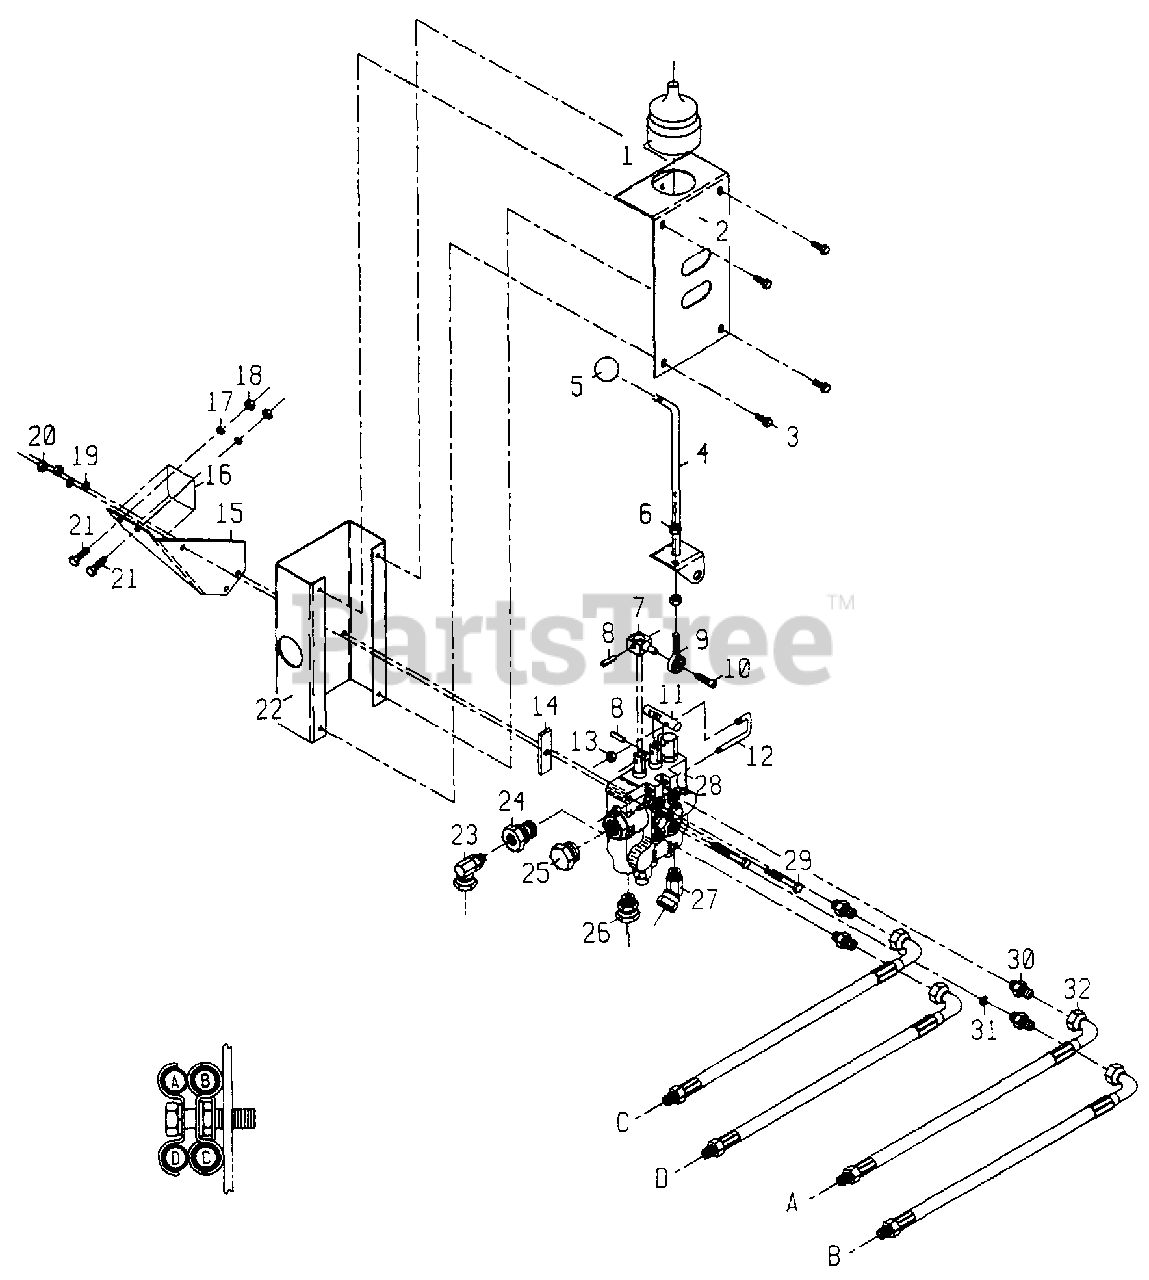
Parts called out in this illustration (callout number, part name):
1	Rubber Boot
2	End Cover
3	1/4 NC x 3/4 Self-tap screw
4	Handle
5	Clip Ball
6	5/16 NF Hex nut
7	Pivot block
8	1/4 x 7/8 Roll Pin
9	Rod End Ball Joint
10	1/4 x 1 Socket Capscrew
11	Pin
13	1/4 NC Self-lock hex nut
15	Valve Mounting Bracket
16	Decal - Control Valve
17	3/8 Lockwasher
18	3/8 NC Hex nut
19	1/4 Lockwasher
20	1/4 NC Hex nut
21	3/8 NC x 1 Capscrew
22	Valve Cover
23	90ø Elbow
24	Power Beyond Sleeve
25	Cap Plug
26	Straight Adapter
27	45ø Adjustable Female Pipe Swivel
28	Valve
29	1/4 NC x 2-1/4 Capscrew
30	Straight adapter
31	Plate orifice
32	Hydraulic hose - L18
